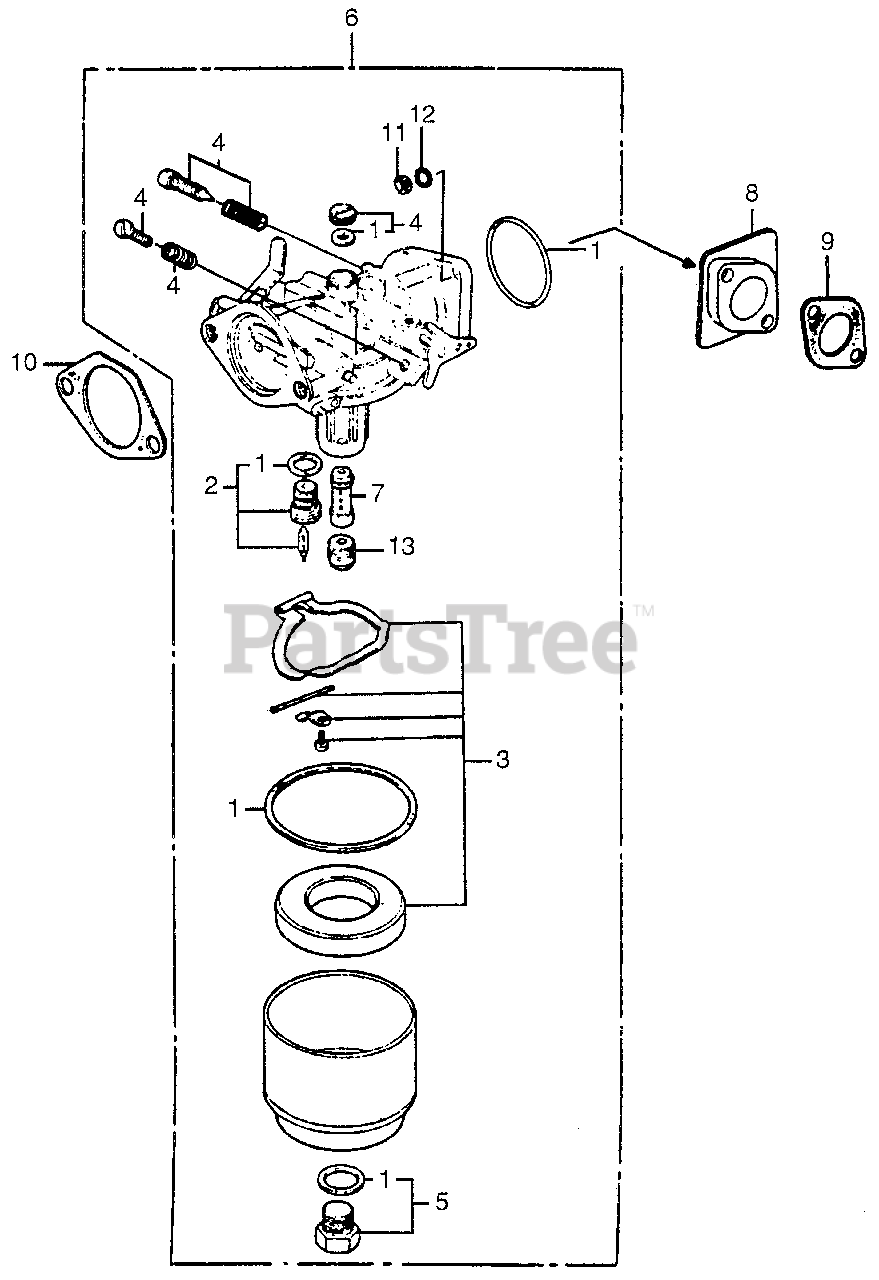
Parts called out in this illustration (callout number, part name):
1	GASKET SET
2	VALVE SET, FLOAT
3	FLOAT SET
4	SCREW SET A (NOT AVAILABLE)
5	SCREW SET (NOT AVAILABLE)
6	CARBURETOR (N/A: SEE COMPONENTS)
7	NOZZLE, MAIN (NOT AVAILABLE)
8	INSULATOR, CARBURETOR (NOT AVAILABLE)
9	GASKET, CARBURETOR INSULATOR (NOT AVAILABLE)
10	GASKET, AIR CLEANER (NOT AVAILABLE)
11	NUT, HEX. (6MM)
12	WASHER, SPRING (6MM)
13	JET, MAIN (#78) (NOT AVAILABLE)
13	JET, MAIN (#80)
